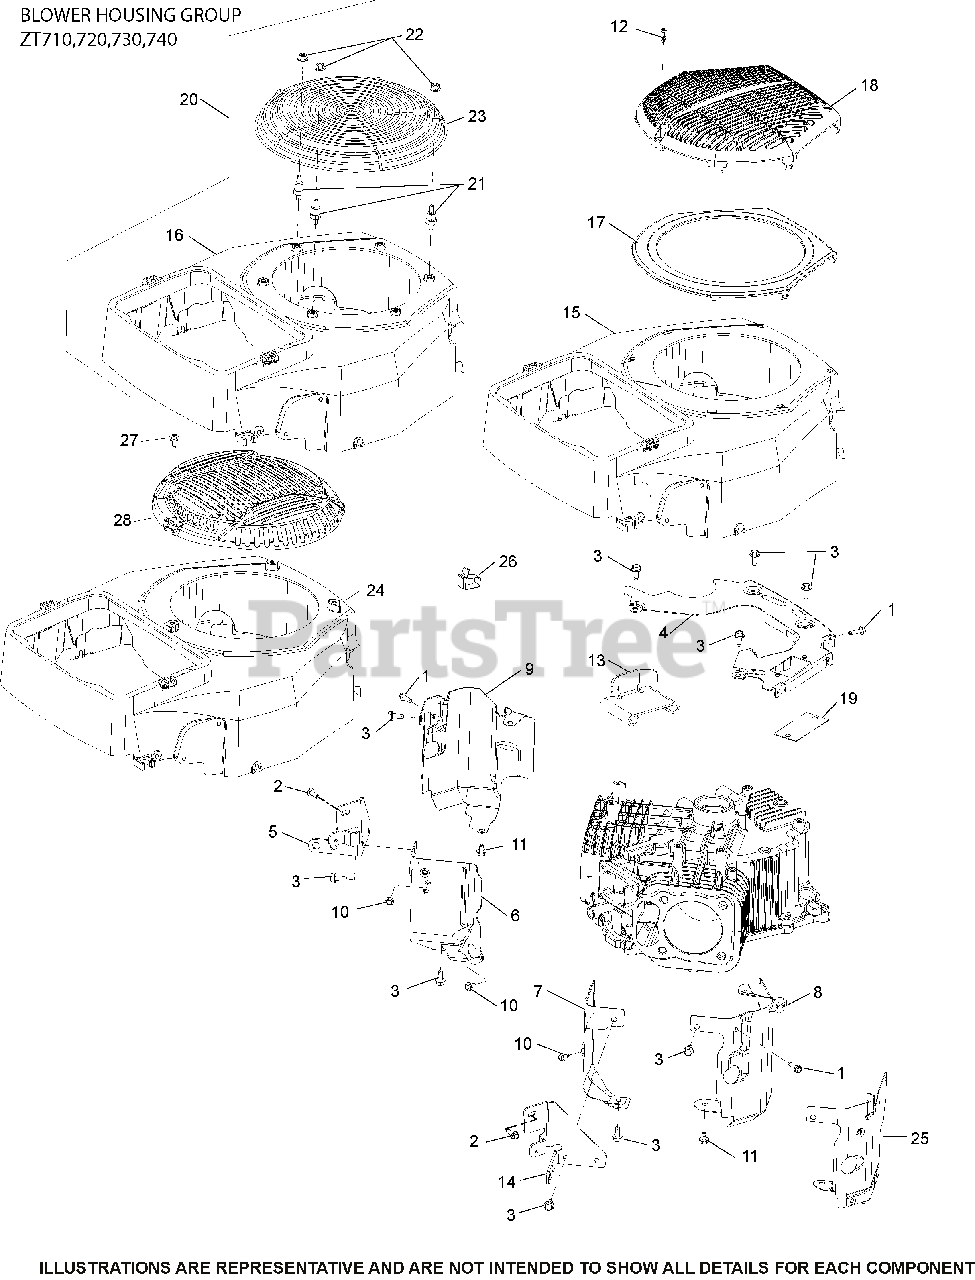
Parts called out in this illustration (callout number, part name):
1	SCREW, THREAD FORMING - USE 25 086 473-S
2	SCREW, HI-LOW
3	SCREW, THREAD FORMING
4	PLATE, BACKING
5	BRACKET, AIR CLEANER BASE (#1 SIDE)
6	VALLEY, BAFFLE #1
7	BAFFLE, VALLEY #2 USE 32 063 21-S
8	BAFFLE, LEFT BARREL
9	BAFFLE, RIGHT BARREL
10	SCREW, THREAD FORMING
12	SCREW, M5-2.42 (PT) THREAD
14	BRACKET, AIR CLEANER BASE (#2 SIDE)
15	KIT, BLOWER HOUSING
18	GUARD, FIXED
